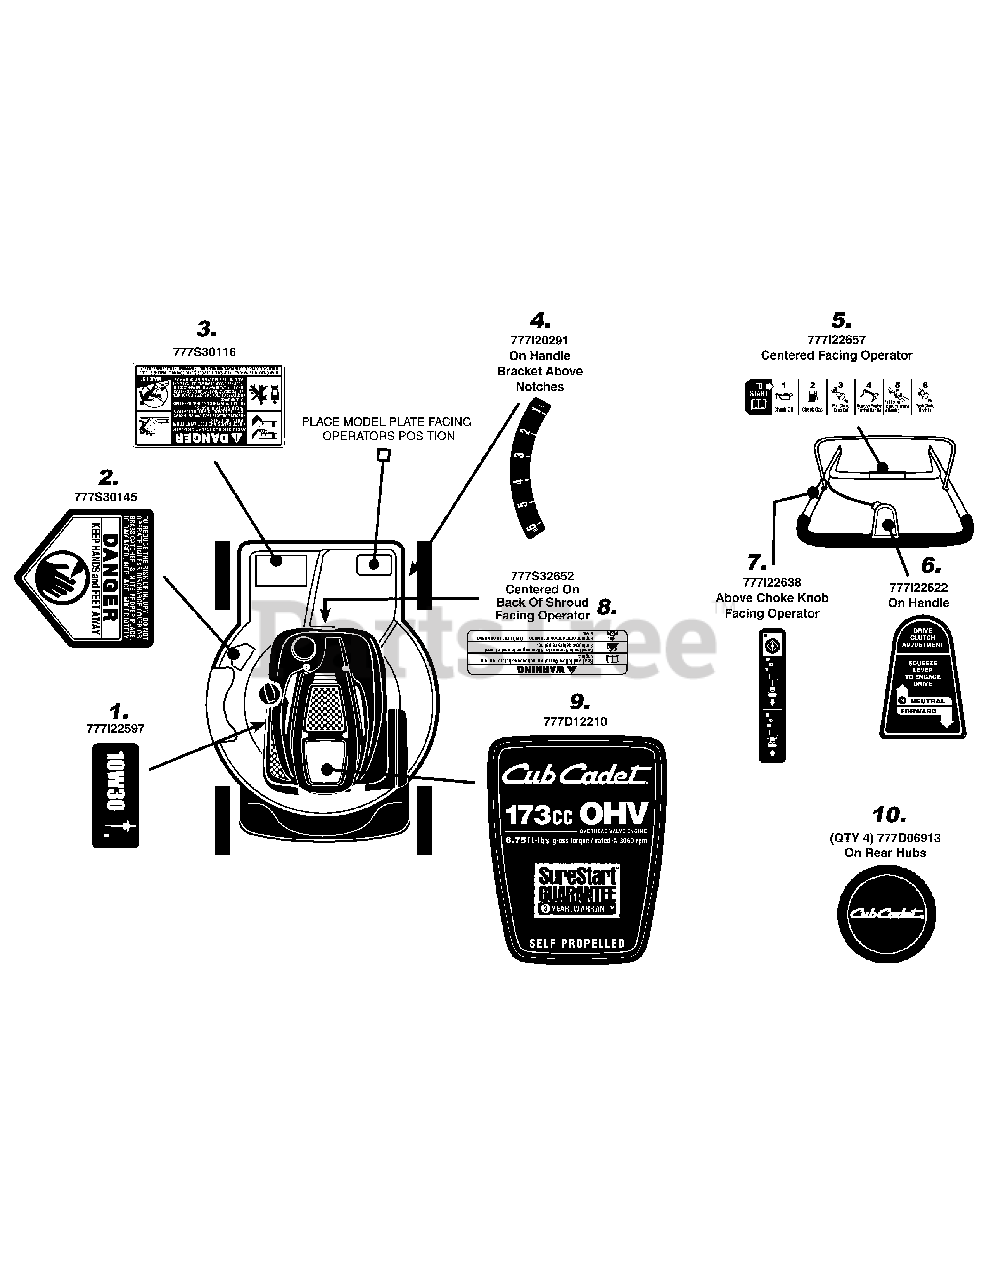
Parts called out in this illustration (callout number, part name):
1	LABEL:MOWER SHROUD
2	LABEL
3	LABEL-MOWER DANGER
4	LABEL-HEIGHT ADJUS
5	LABEL-MOWER HANDLE
6	LABEL-REAR WHEEL CONTROL LEVER
7	LABEL-MOWER HANDLE:CHOKE START/RUN
8	LABEL:MOWER:ENGINE SHROUD
9	LABEL-173CC SHROUD OHV SELF PROPEL
10	LABEL-HUB CAP
